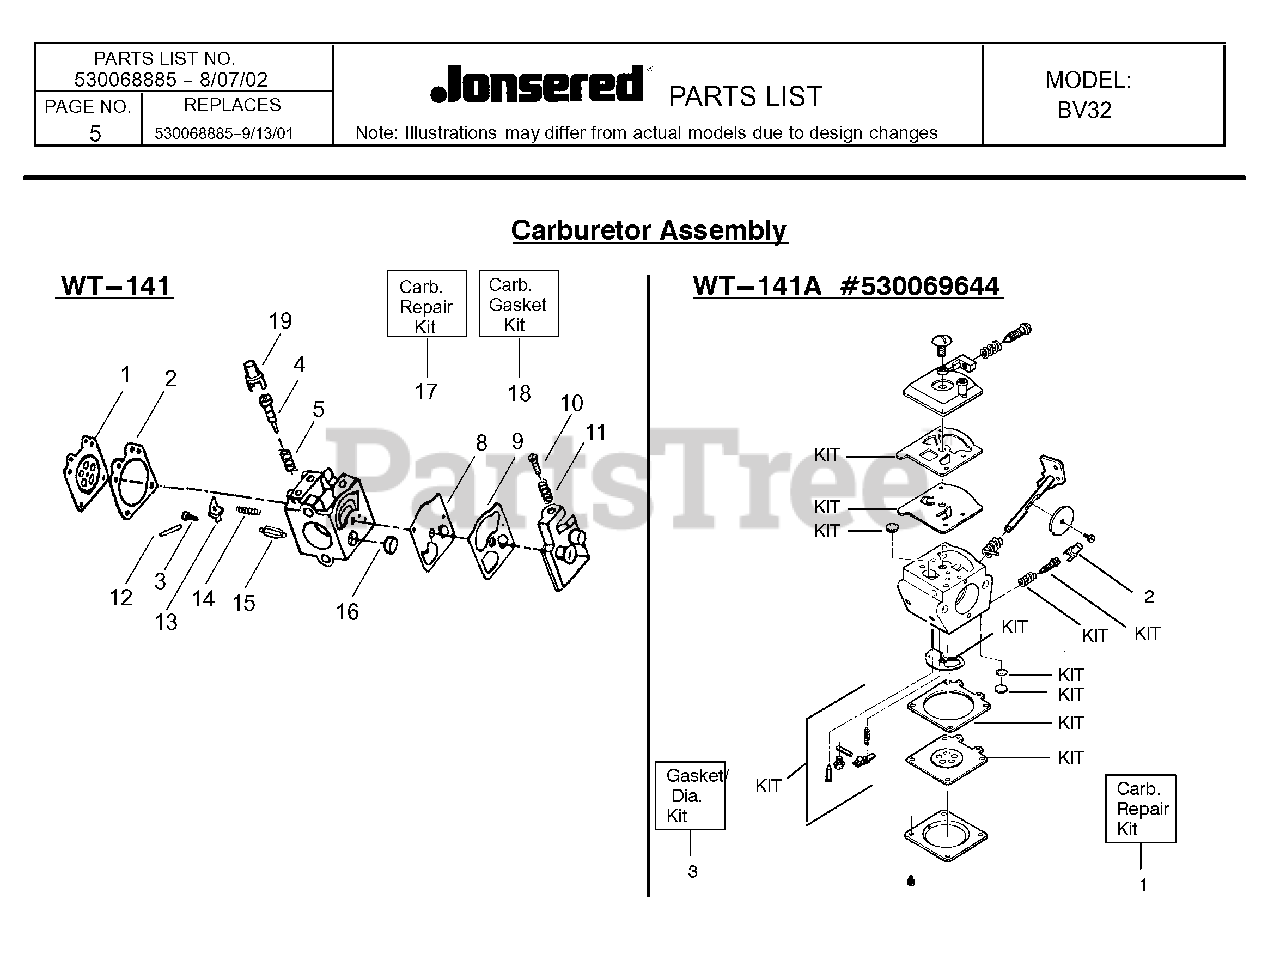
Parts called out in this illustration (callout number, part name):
1	KIT-CARB. KWIK REPAIR
2	LIMITER CAP
3	GASKET/DIAPHRAGM KIT
